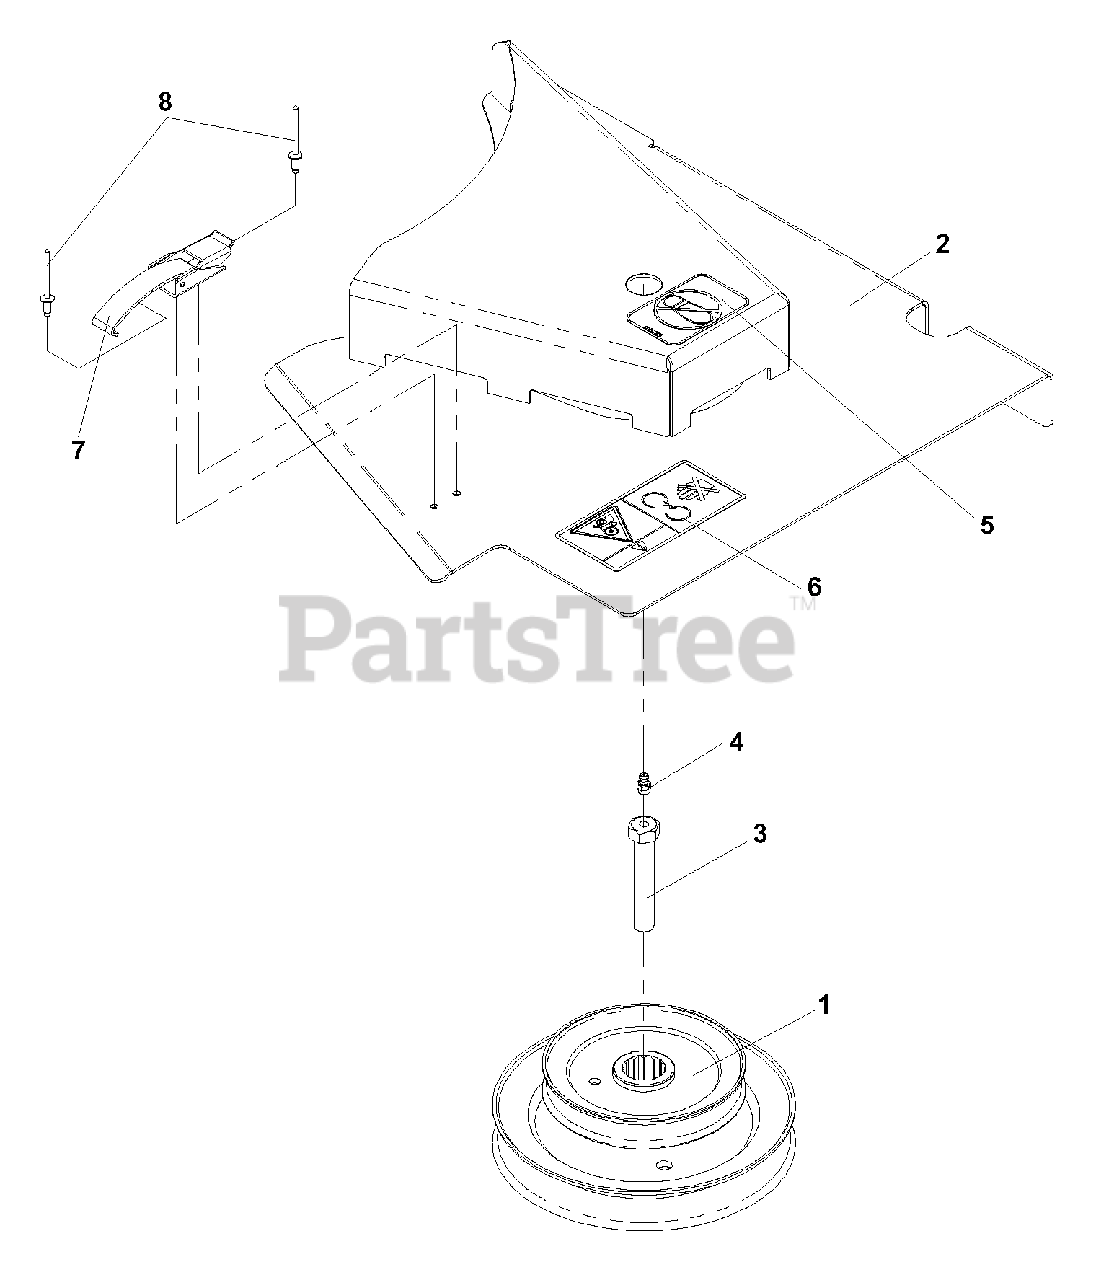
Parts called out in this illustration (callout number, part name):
1	PULLEY, DBL STK, 72"
2	BELT SHIELD, 72"
3	HCS, 7/16 -20 x 2 1/2, GR8
4	ZERK
5	DECAL, EURO NO STEP
6	DECAL, EURO DANGER BELT
7	DRAW LATCH
